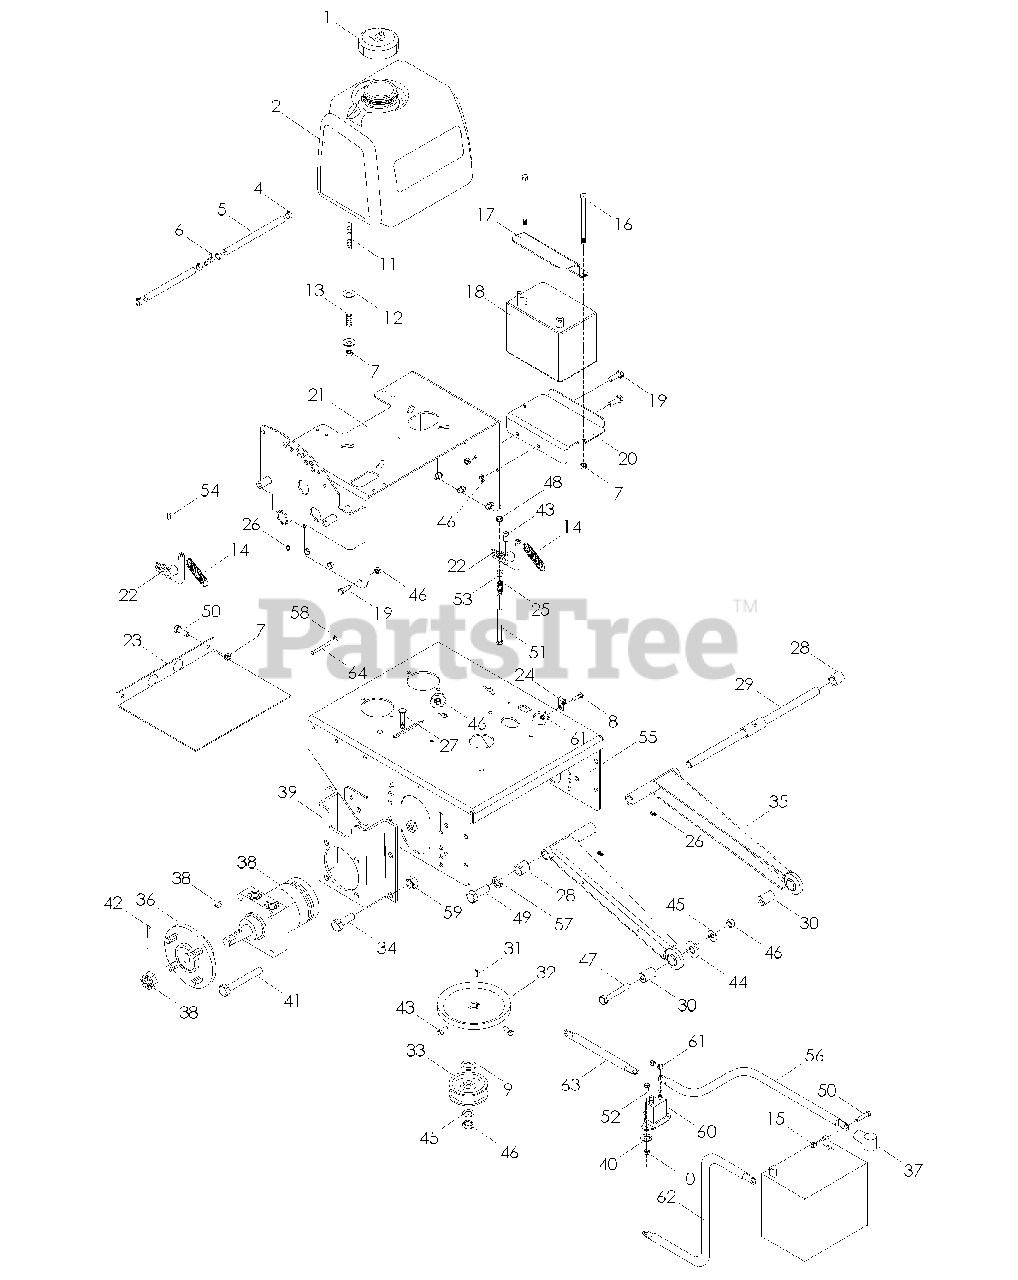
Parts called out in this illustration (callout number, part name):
1	CAP, FUEL
2	TANK, FUEL
3	NUT 1/4-20 THIN NYLOC
4	CLAMP, HOSE
6	VALVE, FUEL
7	NUT 5/16-18 HEX NYLOC
8	HCS 1/4-20 x 3/4
9	WASHER 3/8
10	NUT 1/4-20 CNTRLK
12	WASHER 5/16 STD FLT
14	SPRING, PUMP
15	NUT 5/16-18 HEX CTRLK
16	HCS 5/16-18 x 7
17	STRAP, BATTERY
18	BATTERY, DRY
19	HCS 3/8-16 x 3/4
20	TRAY, BATTERY
21	SUPPORT, TANK
23	SHIELD, BELT
26	ZERK
27	RHSNB 3/8-16 x 2
29	SHAFT, STRUT
30	SPACER, FRONT
31	KEY, METRIC
33	PULLEY, IDLER
34	HFCS 1/2-13 x 1 1/4
38	MTR, HYDRO W/KEY, NUT
39	MOUNT, MOTOR
40	LOCKWASHER IT 1/4
41	HCS 1/2-13 x 2 3/4
42	COTTER PIN
43	SCREW 5/16-18 x 5/8 SET
44	WASHER 1/2 STD FLT
45	WASHER 3/8 FLAT
46	NUT 3/8-16 HEX CNTRLK
47	HCS 3/8-16 x 2 1/4
48	NUT 3/8-16 HEX NYLOC
49	HCS 1/2 x 1
50	HCS 5/16-18 x 3/4
51	HCS 3/8-16 x 2 3/4
52	HCS 1/4-20 x 5/8
54	SCREW 5/16-18 x 5/8
55	DECK W/DECALS, REAR
56	CABLE, POSITIVE
57	LOCKWASHER 1/2
59	NUT 1/2-13 HEX NYLOC
61	NUT 1/4-20 HEX NYLOC
62	CABLE, NEGATIVE
63	CABLE, POSITIVE
64	PIN, CLEVIS
